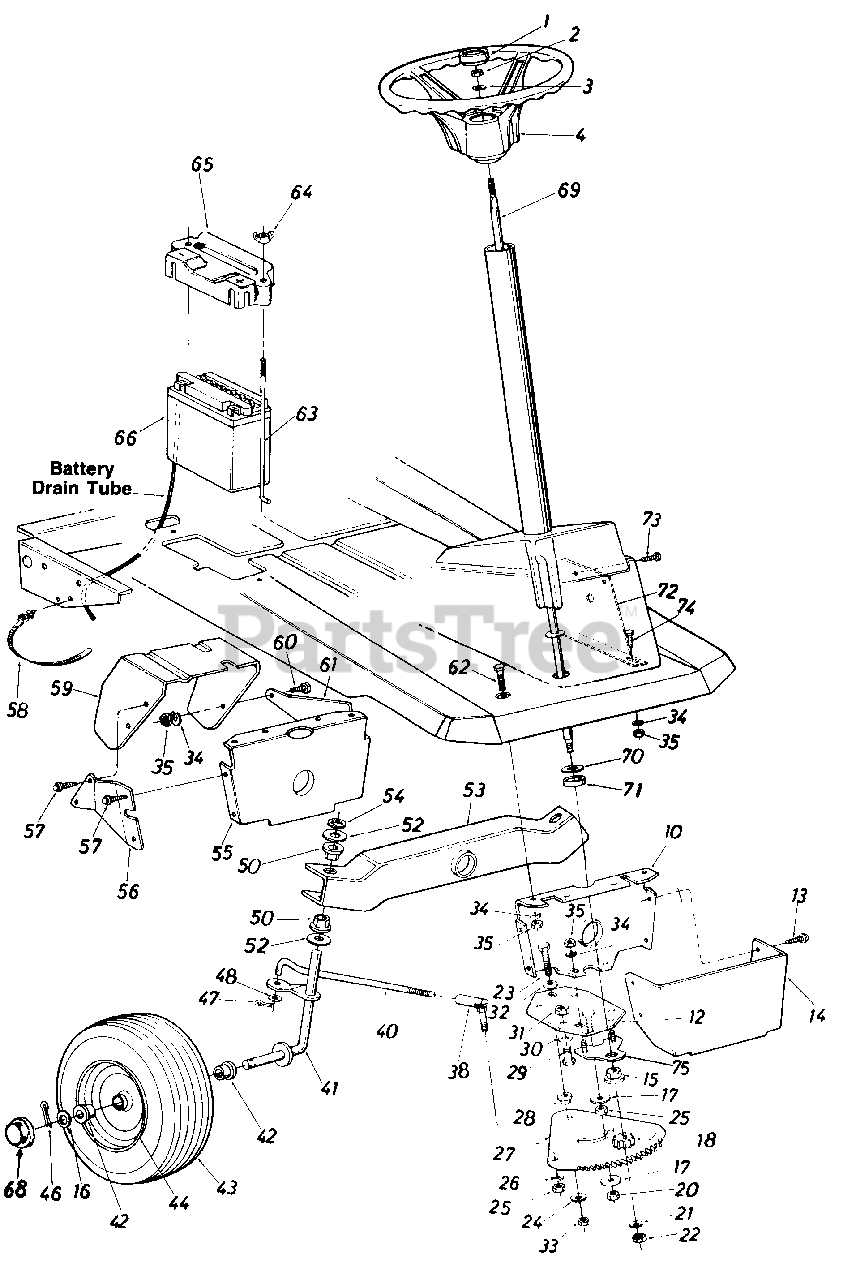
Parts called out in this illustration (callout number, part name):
1	Steering Wheel Cap
2	Hex L-Nut 5/16-24 Thd.
3	Bell-Wash. .345" I.D. x .88" O.D.
4	Steering Wheel Ass'y.
10	Pivot Bar Bracket
12	Steering Gear Support Brkt.
13	Hex Wash. Hd. AB-Tap Scr. 1/4 X .62" Lg.
16	Fl-Wash. .64" I.D. x 1.5" O.D.
17	Fl-Washer 3/8" I.D. x 1.37" O.D.
18	Steering Pinion Gear
20	Hex L-Nut 3/8-24
21	Fl-Wash. .34" I.D. x .68" O.D.
22	Hex L-Nut 5/16-24 Thd.
23	Hex Bolt 3/8-24 x 1.5" Lg. (Grade 5)
24	Fl-Wash. .385" I.D. x 1.38"
25	Hex Nut 3/8-24 Thd.
26	L-Wash. 3/8" I.D.
27	Steering Gear Segment
28	Shoulder Spacer .622" Dia. x .21 8
29	Hex Bolt (Nylon) 1/2-13 x .75"
30	Fl-Wash. .530" I.D. x .930"
31	Hex Nut 1/2-13 Thd.
32	Bell-Wash. .385" I.D. x .88"
33	Hex Nut 3/8-24 Thd.
34	L-Wash. 5/16" I.D.
35	Hex Nut 5/16-18 Thd.
38	Ball Joint Ass'y. 3/8-24 Thd.
40	Steering Tie Rod
41	Front Axle Ass'y. R.H.
42	Flange Bearing .632" I.D.
43	Front Wheel Ass'y. Comp.
44	Front Wheel Rim Only
46	Cotter Pin 1/8" Dia. x 1.25"
47	Cotter Pin 1/8" Dia. x 1.00"
48	Fl-Wash. .385" I.D. x .87"
50	Hex Flange Bearing
52	Fl-Wash. .635" I.D. x 1.12"
53	Pivot Bar Ass'y.
54	Speed Nut 5/8" I.D.
55	Pivot Bar Bracket
56	Bracket Reinforcement R.H.
57	Hex Wash. Hd. AB-Tap Scr. 1/4 X .62" Lg.
58	Cable Tie
59	Clutch-Brake Pedal Ass'y.
60	Hex Bolt 5/16-18 x .75" Lg.
63	Battery Hold Down Rod
64	Wing Nut Solid 1/4-20 Thd.
65	Battery Hold Down Cover
66	12V Battery
68	Hub Cap
69	Steering Shaft Ass'y.
70	Fl-Wash. .62" I.D. x 1.25" O.D.
71	Spacer (Plastic)
74	Hex Bolt 5/16-18 x 2.00" Lg.
75	Steering Gear Adjuster Ass'y.
